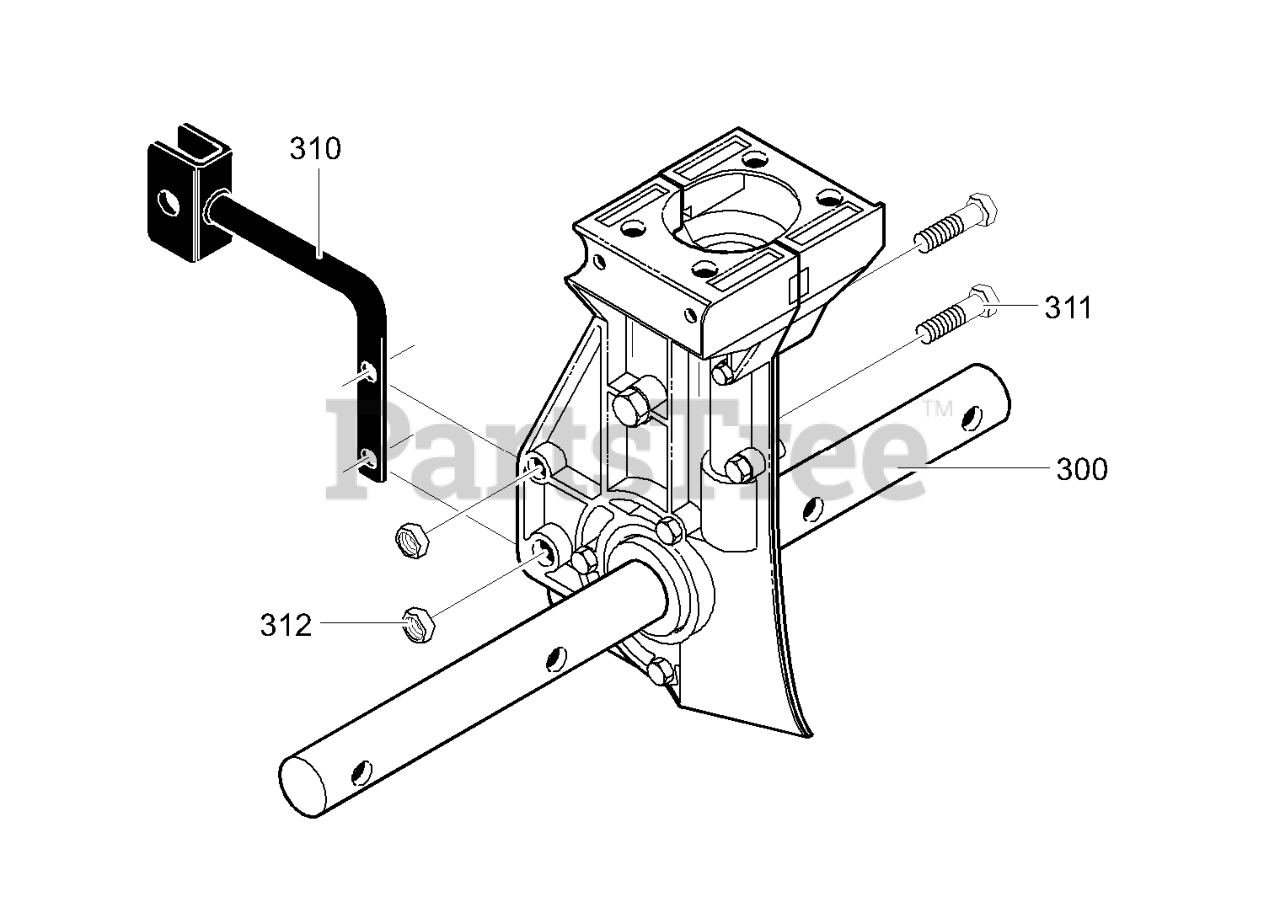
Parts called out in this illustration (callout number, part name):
300	Transmission
310	Bracket, Depth Rod
311	Screw, 1/4-20x1.25
312	Nut, 1/4-20
